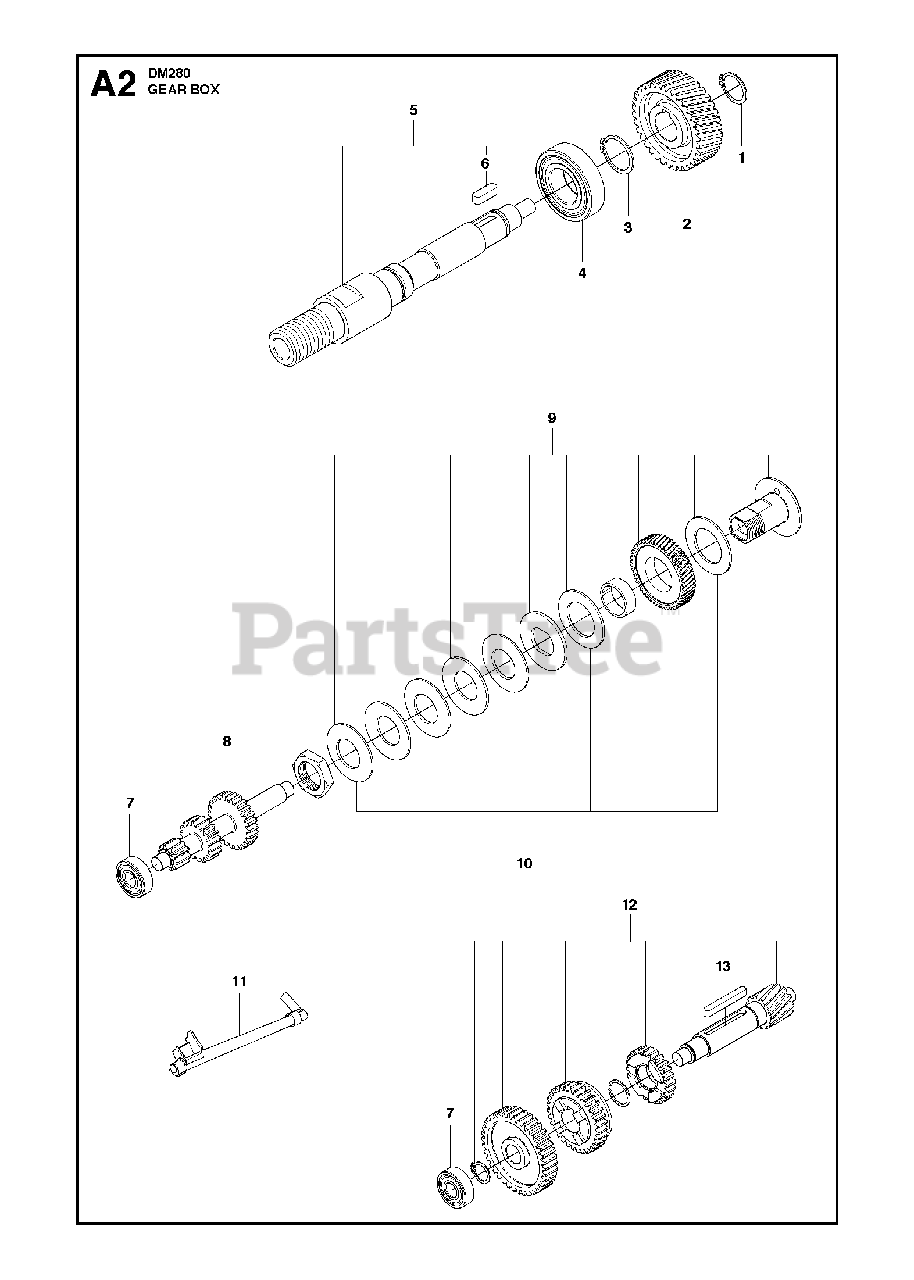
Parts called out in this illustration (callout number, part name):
2	GEAR WHEELLow speed version
2	GEAR WHEELHigh speed version
7	BALL BEARING
12	GEAR WHEELLow speed version
12	GEAR WHEELHigh speed version
